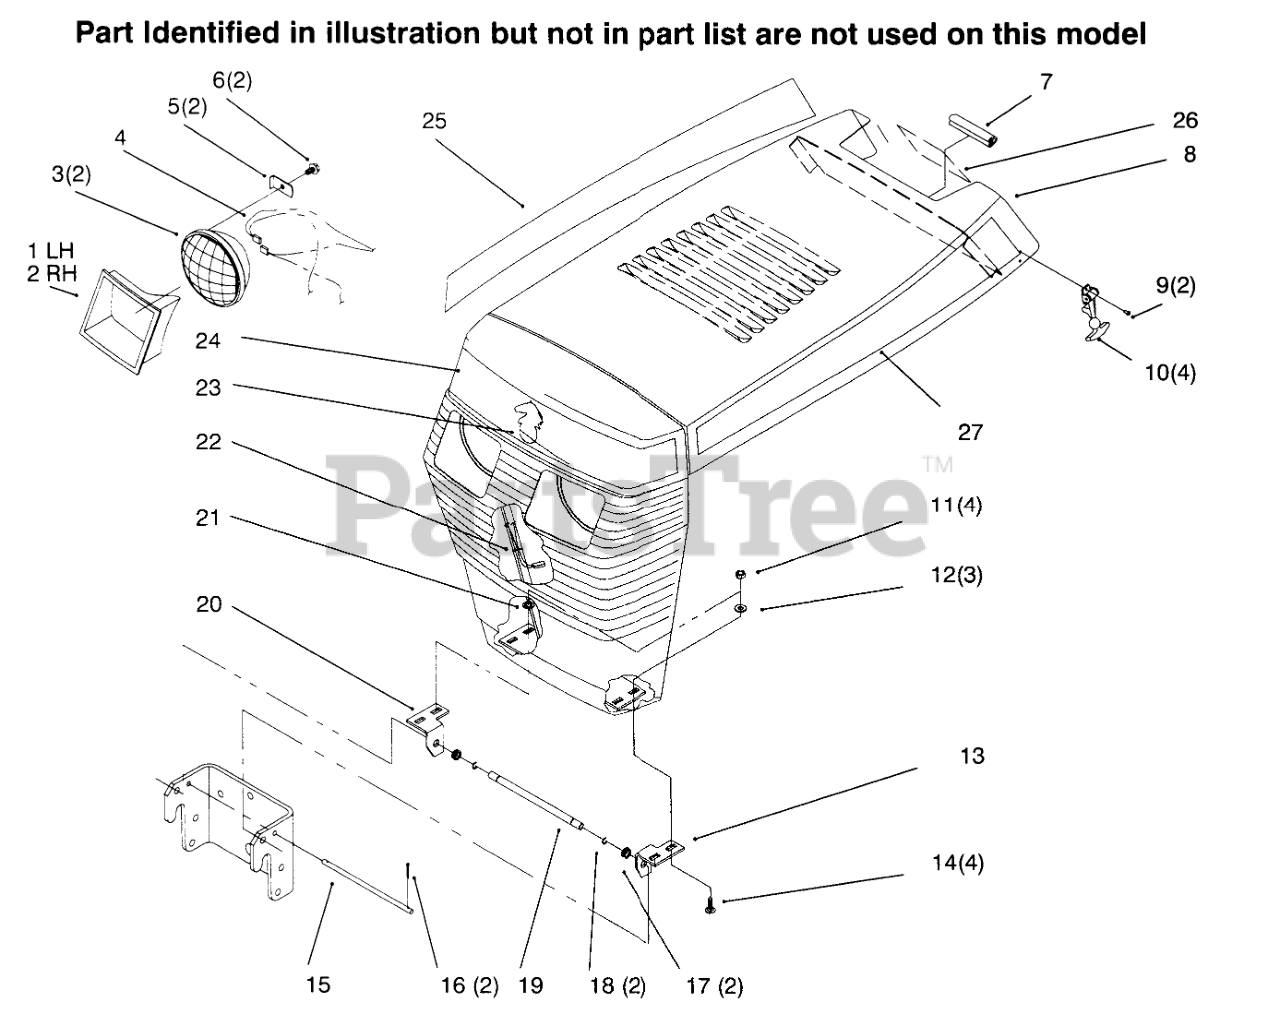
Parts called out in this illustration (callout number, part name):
1	BEZEL-HEADLIGHT, LH
2	BEZEL-HEADLIGHT, RH
3	HEADLAMP
4	LIGHT GROUND WIRE
5	LOCK-HEADLIGHT
6	SCREW-HWH
7	EDGING-CONSOLE
8	Hood
9	RIVET-POP
10	HANDLE ASM
11	NUT-LOCK, NI
12	WASHER-FLAT
13	BRACKET-GRILL, LH
14	SCREW-CARR
15	ROD-HOOD STOP
16	PIN-COTTER
17	BUSHING-NYLINER
18	RING-RETAINING
19	ROD-GRILL PIVOT
20	BRACKET-GRILL, R H
21	WASHER-LOCK, INTERNAL
23	LOGO (GOLD)
24	DECAL-FRONT HOOD, TOP
25	DECAL - RH HOOD TOP
26	DECAL - DANGER
27	DECAL - LH HOOD TOP
